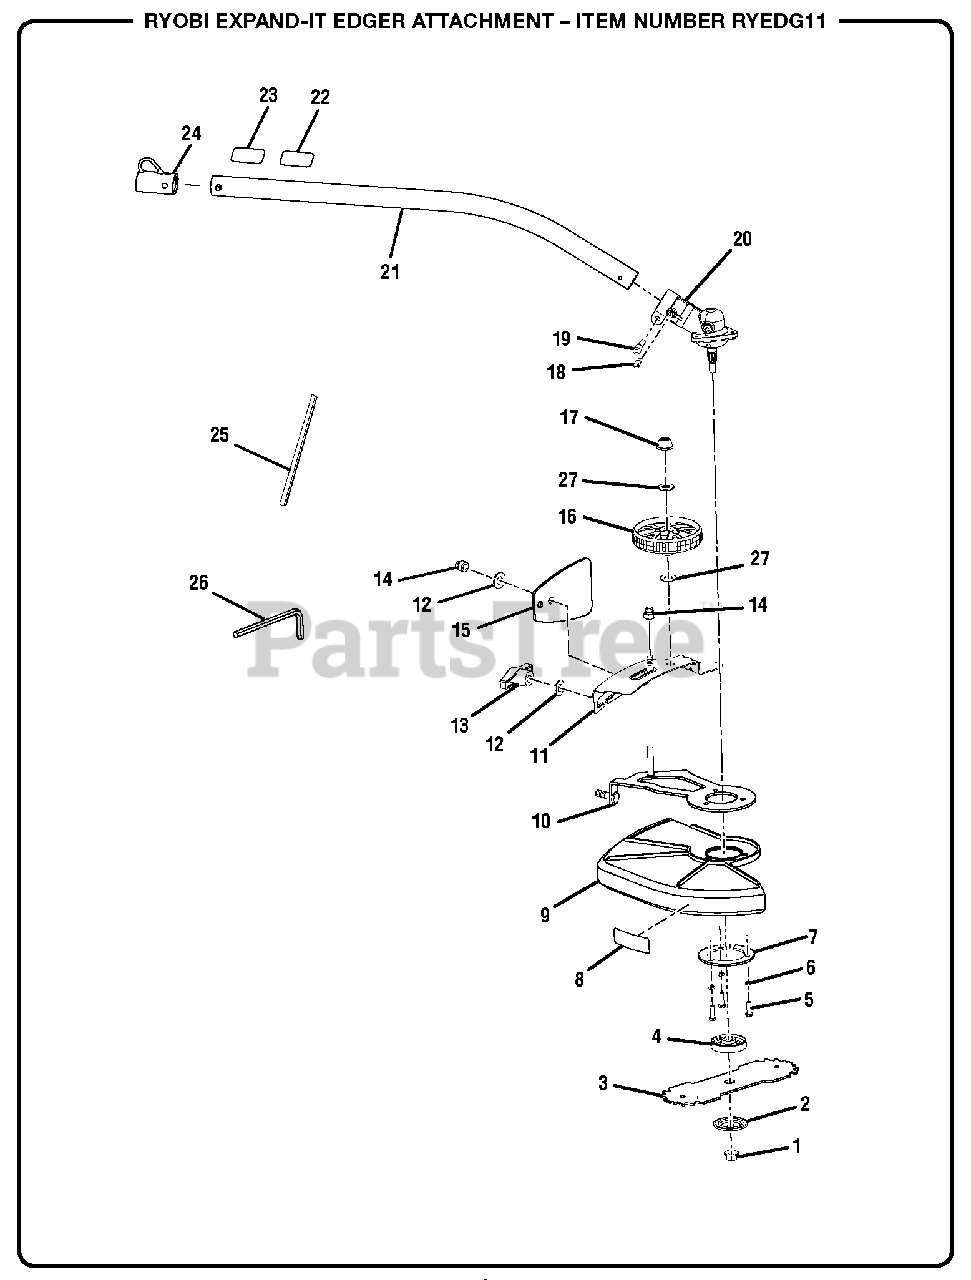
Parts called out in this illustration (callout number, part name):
1	Blade Nut (M8, Left Hand Threads)
2	Cupped Washer
4	Flanged Washer
5	Screw (10-24 x 5/8in. Hex Hd.)
6	Lock Washer (5 mm)
7	Ring Washer
8	Warning Decal
9	Blade Guard
10	Main Frame
11	Wheel Frame
12	Washer (10 mm)
13	Adjusting Knob w/Hex Nut
14	Hex Nut w/Nylon Cap (5/16-18)
15	Debris Flap
16	Guide Wheel
17	Push Nut
18	Screw (10-24 x 5/8 in., Hex Soc. Hd)
19	Screw (1/4-20 x 1-1/4 in., Hex Soc. Hd)
20	Gear Head Assembly
21	Drive Shaft Assembly
22	Logo Label
23	Warning Label
24	Hanger Cap
25	Holding Pin
26	Hex Key (M4)
27	Washer (ID11 x OD 18 x 2t)
